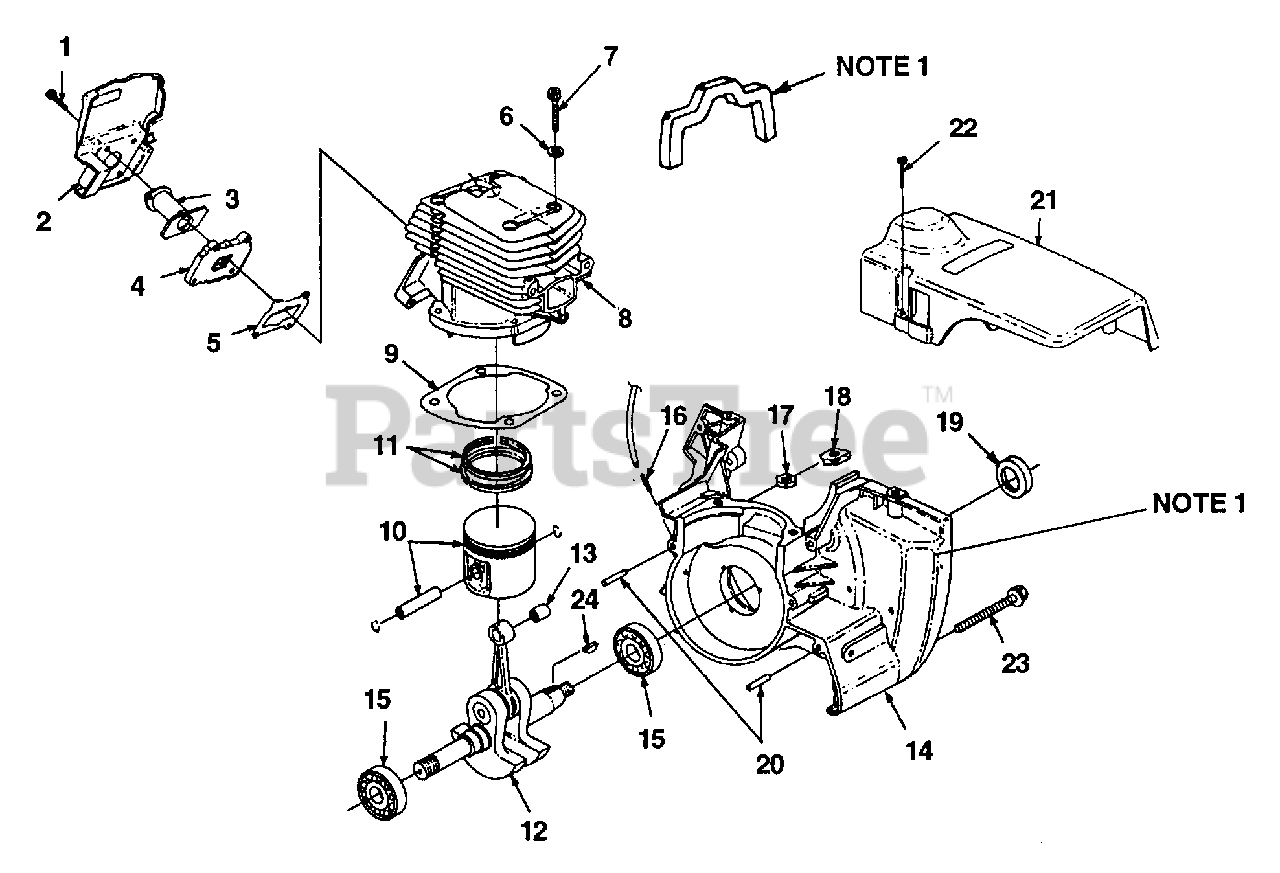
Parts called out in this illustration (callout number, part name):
1	SCREW-Mach. Hex Hd. (10-24 x 1")
2	BAFFLE-Cylinder
3	BOOT-Intake
4	ADAPTER-Intake
5	GASKET-Intake
6	WASHER-Conical (#10)
7	SCREW-Cap Socket (10-24 x 1")
8	CYLINDER & PISTON (Matched)
9	GASKET-CYLINDER
10	PISTON & PIN ASSY.
11	PISTON RING
12	CRANKSHAFT & ROD
13	BEARING-Needle
14	CRANKCASE ASSY.
15	BEARING-Ball
16	FITTING-Tube
17	NUT-Lock Hex (10-24)
18	NUT-Retainer
19	SEAL-Shaft
20	PIN-Dowel
21	COVER-CYLINDER
22	SCREW-CYLINDER COVER
23	SCREW-Hex Sems (10-24 x 2")
24	KEY-Woodruff
NOTE1	FOAM KIT
